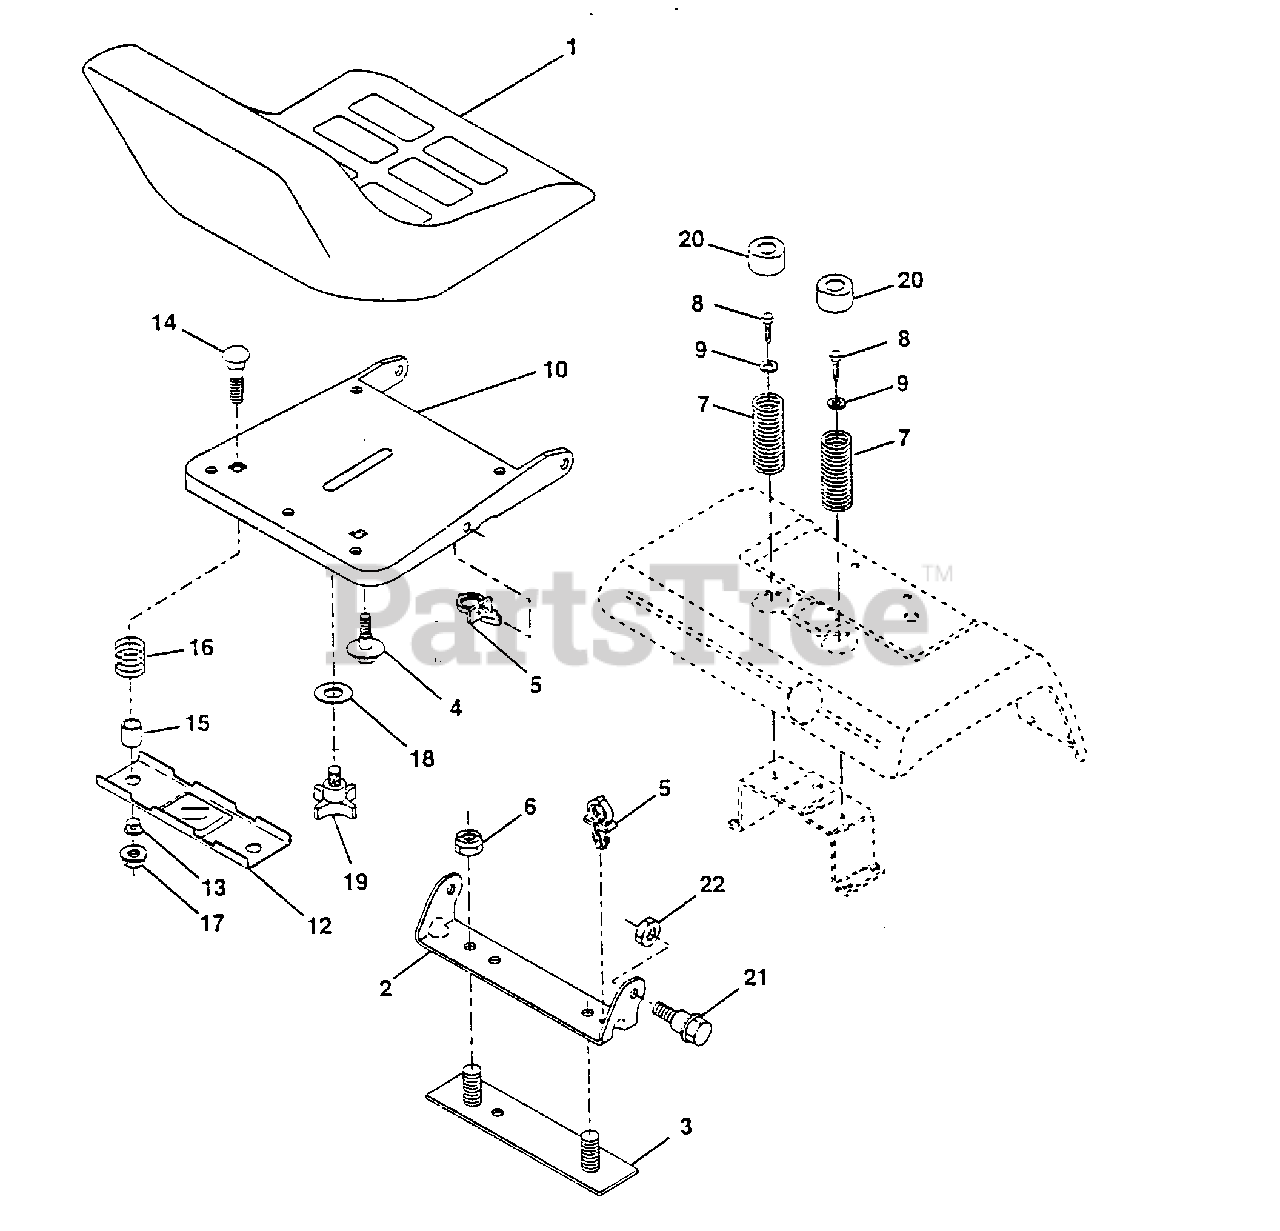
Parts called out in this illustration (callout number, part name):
1	Seat (AYP part number)
2	Bracket, Pivot Seat (AYP part number)
3	Strap, Fender (AYP part number)
4	Bolt, Shoulder 5/16-18 X .62 (AYP part number)
5	Clip, Push In (AYP part number)
6	Loicknut 3/8-16 Unc (AYP part number)
7	Spring, Seat Cprsn (AYP part number)
8	Screw, Thdrol 5/16-18 X 1/2 (AYP part number)
9	Washer 13/32 X 1 X 14 Ga. (AYP part number)
10	Pan, Seat (AYP part number)
12	Bracket, Mounting Switch (AYP part number)
13	Bushing, Snap (AYP part number)
14	Bolt, Carriage 1/4-20 X 1-3/8
15	Spacer, Split (AYP part number)
16	Spring, Cprsn (AYP part number)
17	Nut, Lock 1/4 Lge Flg Gr.5 (AYP part number)
18	Washer 17/32 X 1-3/16 X 12 Ga. (AYP part number)
19	Knob, Seat 1/2-13 Unc (AYP part number)
20	Cap, Spring Seat (AYP part number)
21	Bolt, Shoulder 5/16-18 Unc (AYP part number)
22	Nut, Crownlock 5/16-18 Unc
